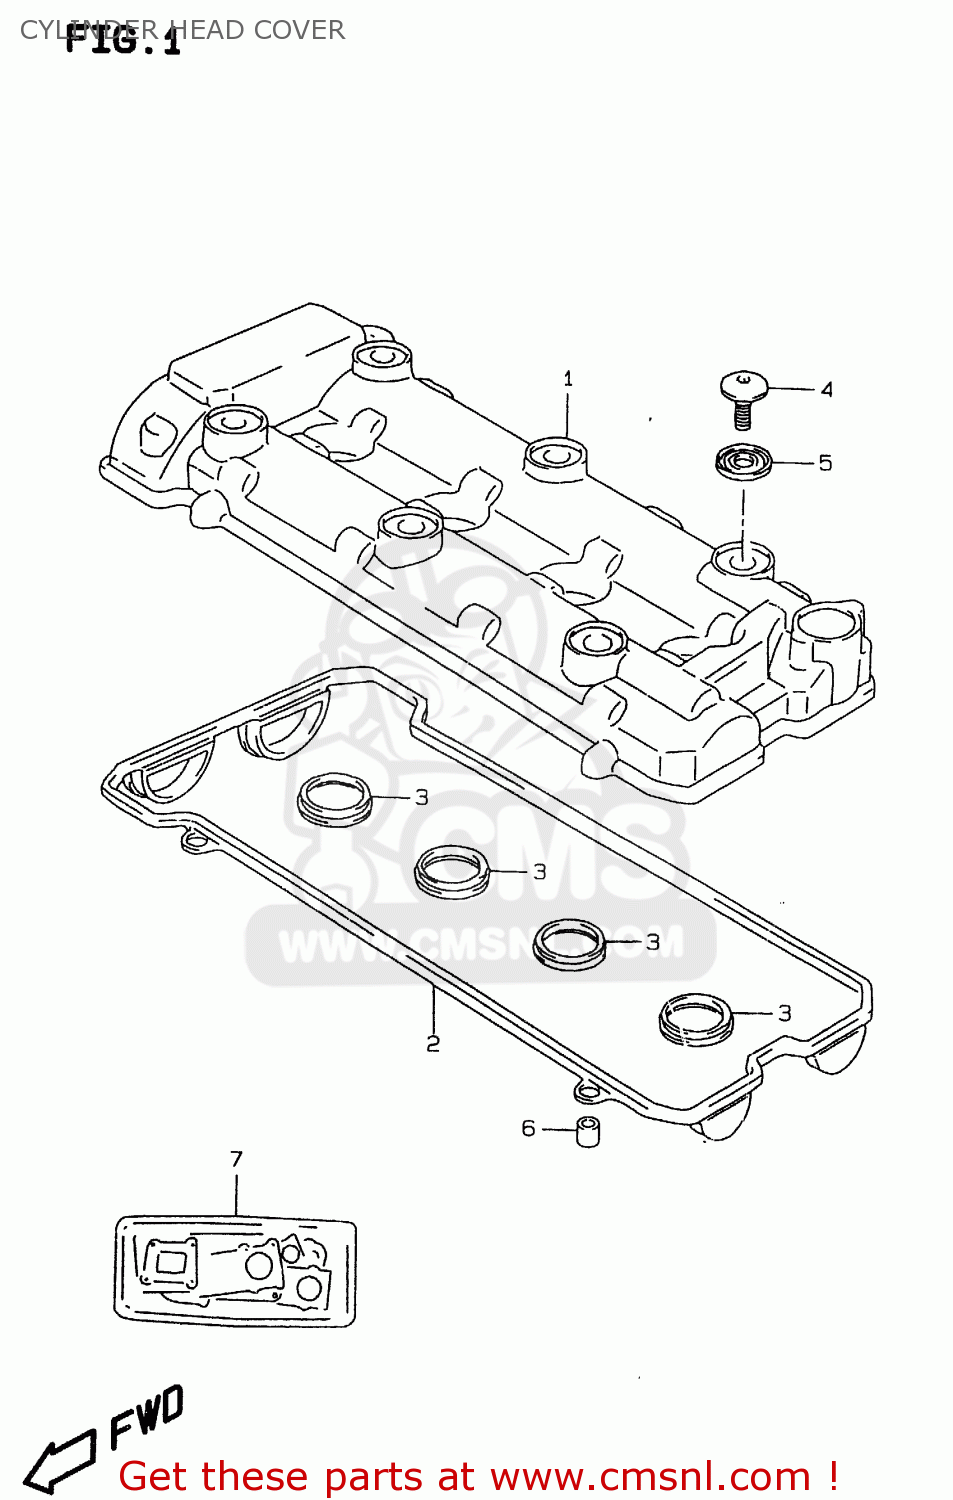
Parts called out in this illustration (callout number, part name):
1	COVER,CYLINDER HEAD
2	GASKET,CYL HEAD COVER NO.1
3	GASKET,CYL HEAD COVER NO.2
4	BOLT(7X17.5)
5	WASHER(10.6X25.5X2.3)
6	PIN(6.2X8X11)
7	GASKET SET (NAS)
